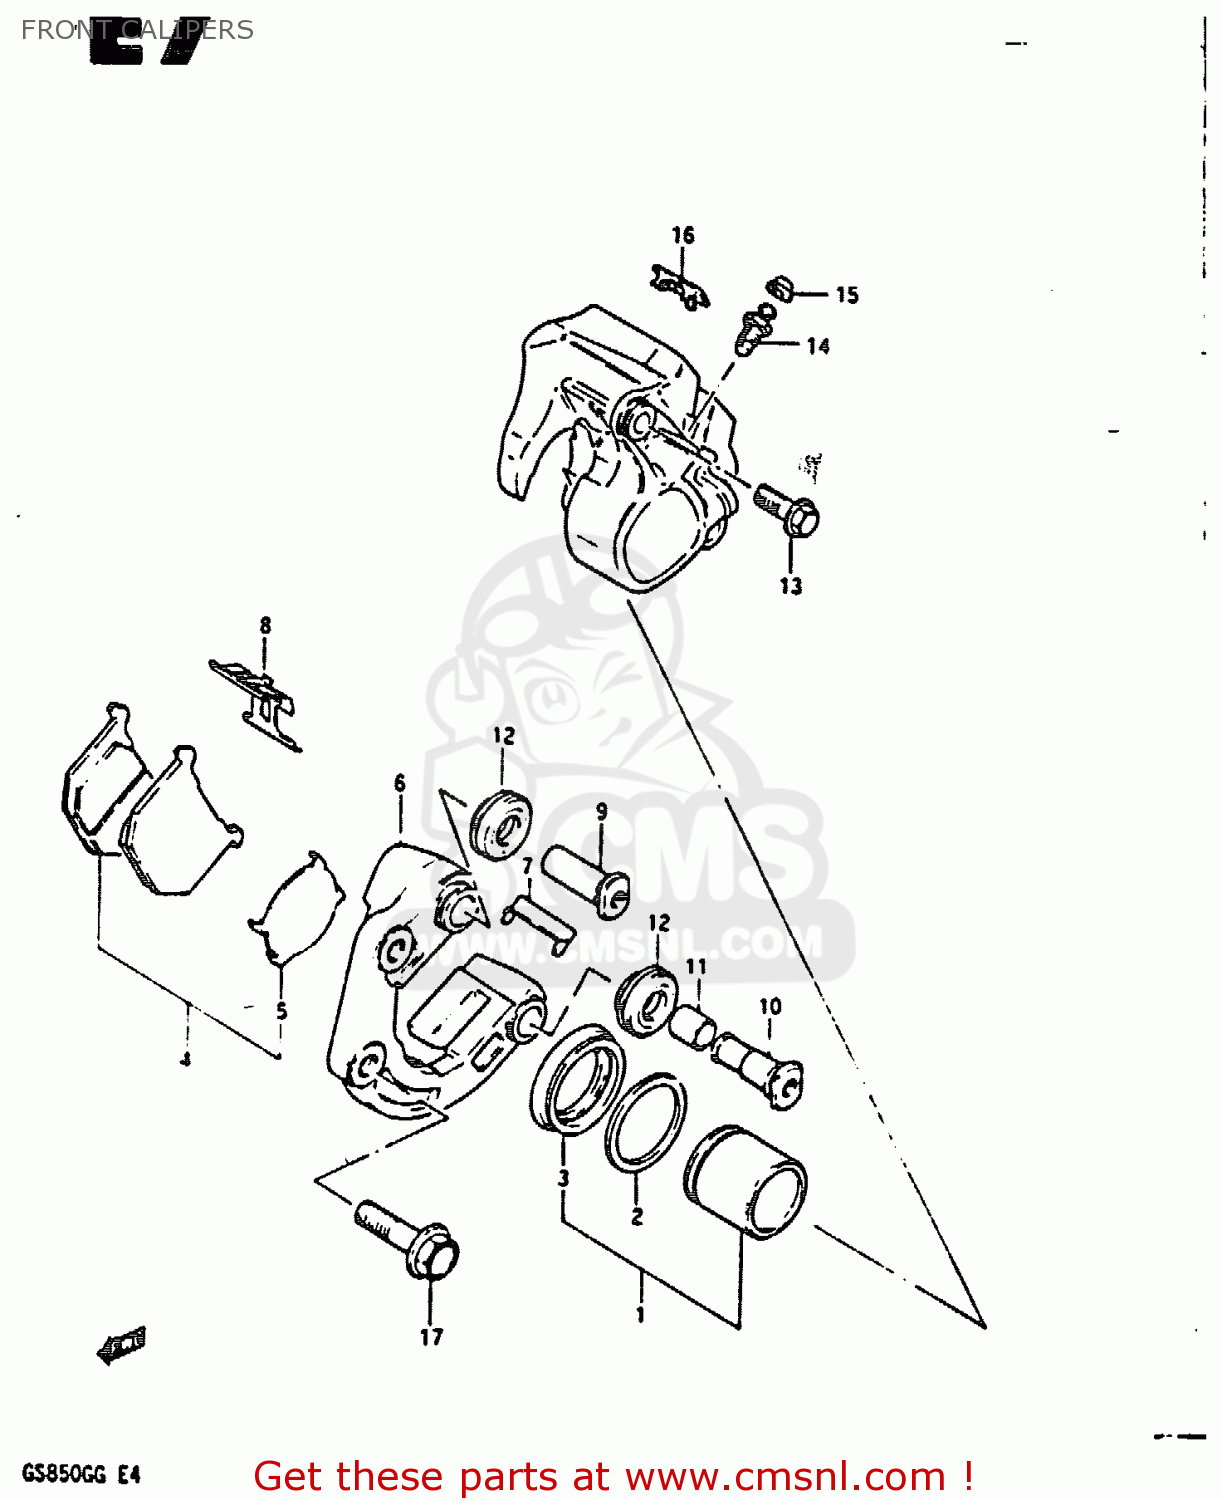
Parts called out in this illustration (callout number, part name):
1	PISTON SET
2	SEAL,PISTON
3	BOOT,PISTON
4	PAD SET,BRAKE (MCA)
5	SHIM,PAD
6	CARRIER,CALIPER,LEFT
7	GUIDE,PAD
8	SPRING,PAD
9	AXLE NO.1
10	AXLE NO.2
11	BUSH,AXLE
12	BOOT,AXLE
13	BOLT
14	BLEEDER
15	CAP,BREATHER
16	COVER
17	BOLT(10X37)
